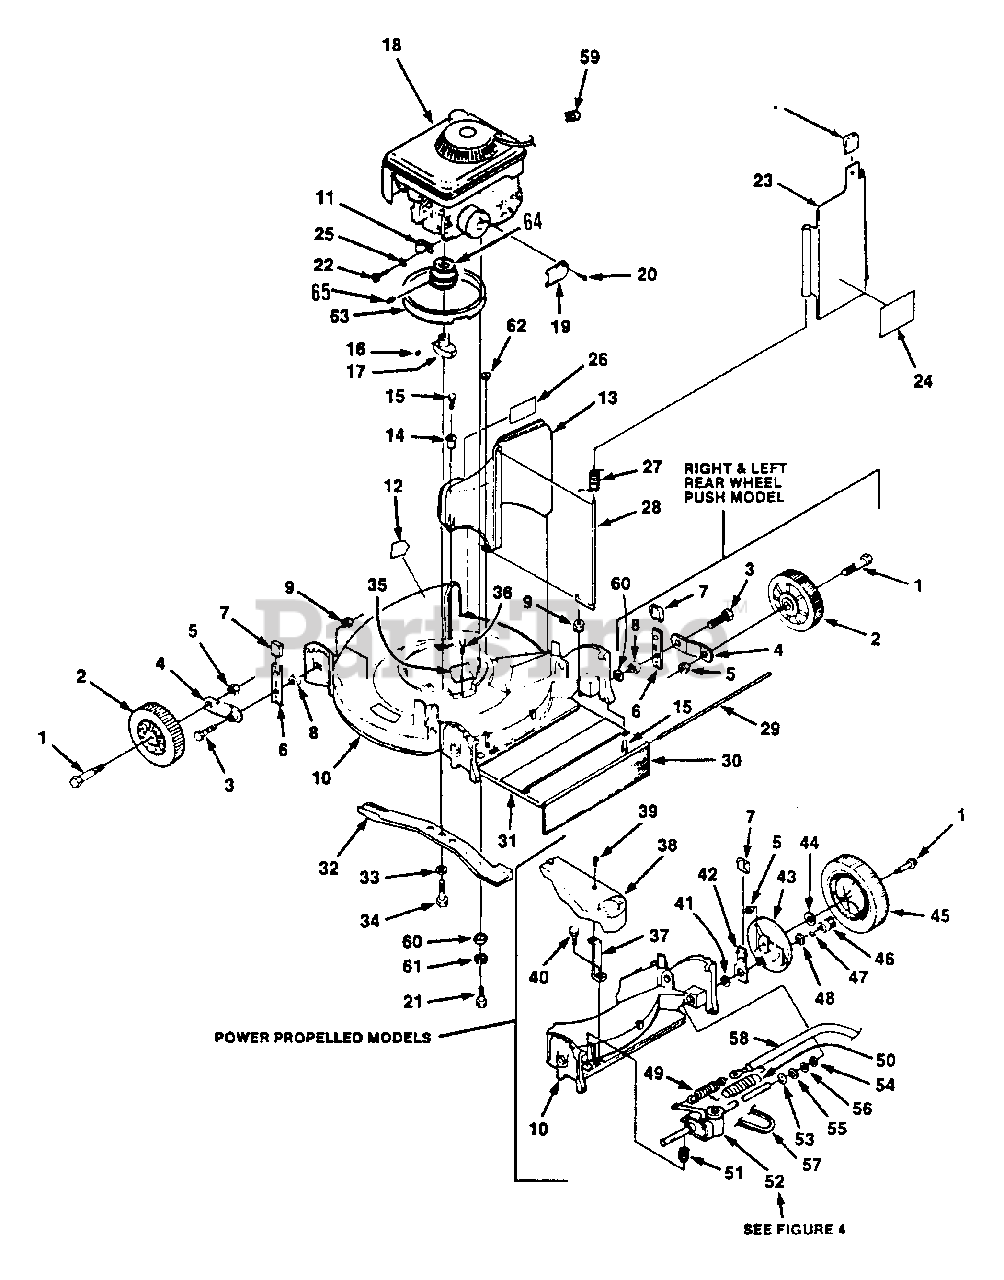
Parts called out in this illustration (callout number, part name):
1	AXLE - ASSY
2	WHEEL ASSY
3	BOLT - 5/16×18
4	ARM - WHEEL ADJUSTING
5	NUT - 3/8-24
6	INDEXING SPRING & PIN ASSY
7	KNOB
8	SPACER
9	NUT - 5/16-18 -- FLANGE
10	DECK - 21"
11	CLAMP
12	LABEL - WARNING
13	CHUTE, DISCHARGE
14	EYELET
15	SCREW - 1/4-20×3/4" -- HEX CAP
16	KEY
17	ADAPTER, BLADE
21	SCREW - 5/16-18×2" -- HEX CAP
23	DOOR, CHUTE
24	LABEL - DOOR
26	LABEL - GASAHOL
27	SPRING
28	PIN, HINGE
29	ROD, DRAG FLAP
30	FLAP, DRAG
31	COVER - REAR
32	BAR, CUTTER - 21"
33	WASHER, LOCK 3/8
34	BOLT, HEX HEAD 3/8"-24×1-1/2"
35	COVER, BELT
36	SCREW - 1/4-20×1/2" -- HEX CAP
37	SUPPORT
38	COVER, DRIVE
44	WASHER
48	WASHER
50	COVER, SPRING
51	SPRING
53	RING
54	WASHER
55	WASHER
56	SHIM
57	BELT, DRIVE
58	CABLE, TRACTION
59	ROPE STOP
60	WASHER - 5/16"
61	LOCKWASHER - 5/16"
62	WASHER - 1/4"
63	RING, ENGINE
